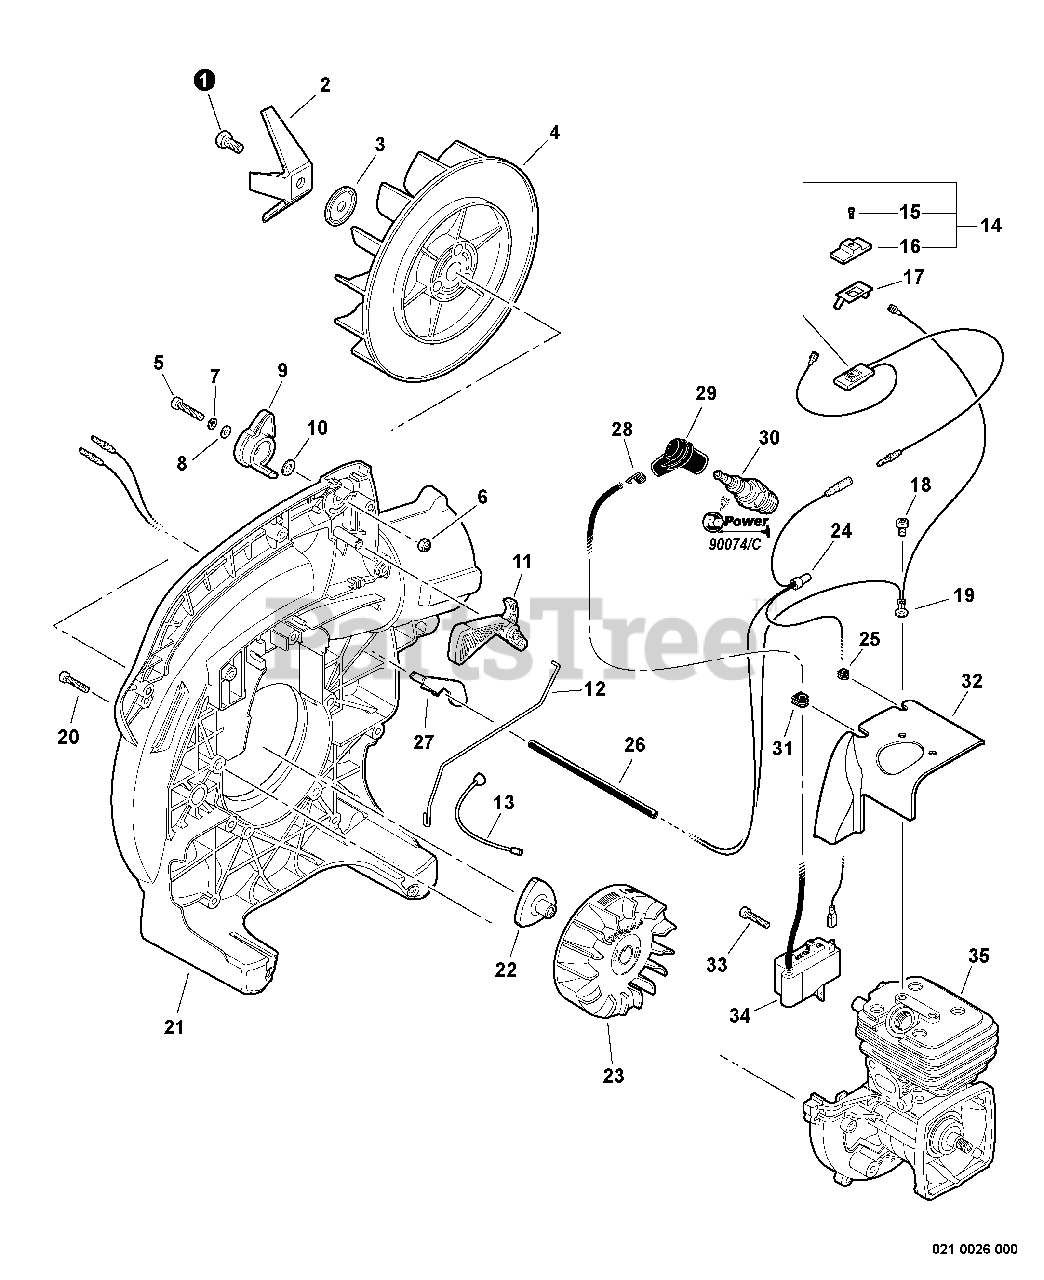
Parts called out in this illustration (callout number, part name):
1	BOLT 8×15
2	CUTTER, SHREDDER
3	WASHER 8.2×31×0.8
5	BOLT, TORX 5×25
6	NUT, LOCK M5
7	WASHER, SPRING 5
8	WASHER 5.5×12×0.8
9	CONTROL, THROTTLE
10	WASHER 5.5×12×0.8
11	TRIGGER, THROTTLE
12	ROD, THROTTLE
13	CABLE, THROTTLE
14	SWITCH ASSY, ON-OFF
15	SCREW 3×10
16	KNOB, SWITCH
17	TERMINAL, LEAD
18	BOLT, TORX 5×8
20	BOLT, TORX 4×20
21	CASE, FAN
22	HUB, FAN
23	FLYWHEEL
26	TUBE, INSULATOR
28	TERMINAL, SPARK PLUG
29	CAP, SPARK PLUG
30	SPARK PLUG - BPM8Y
30	SPARK PLUG - BPMR8Y
32	SHIELD, CYLINDER
33	BOLT, TORX 4×20
34	COIL, IGNITION
35	SHORT BLOCK
36	TUNE-UP KIT - REPOWER
